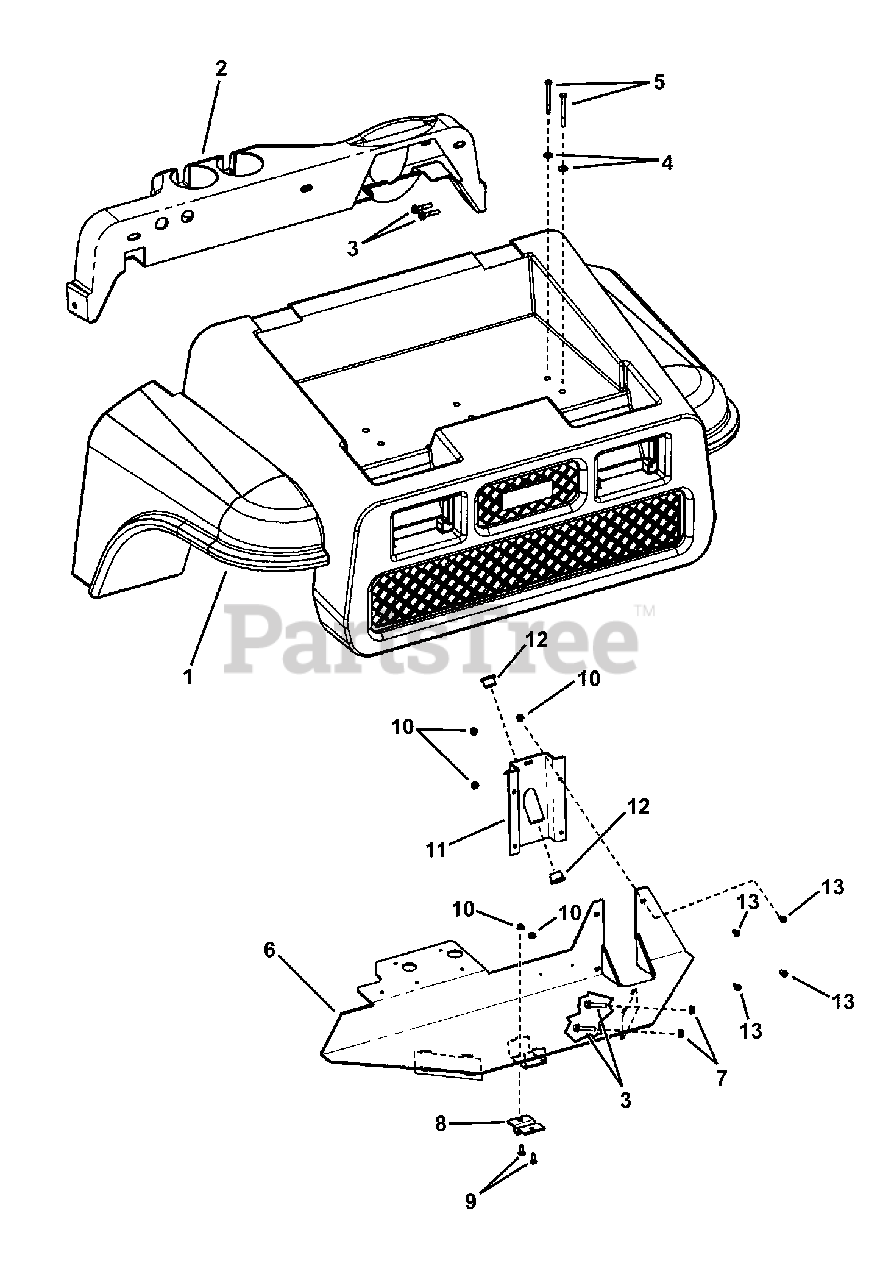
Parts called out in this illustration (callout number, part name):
1	FENDER, UV-2
2	DASH, UV-2
3	BOLT, 5/16-18 x 1-1/2" Hex Flange Lock, GR 5
4	WASHER, .281 x .750 x .051 Flat
5	SCREW, 1/4-20 x 3" Hex Head Cap, GR 5
6	WELDMENT, Steering Support
7	NUT, 5/16-18 Hex Flange Lock, GR 5
8	PIVOT BRACKET, Throttle
9	BOLT, 1/4-20 x 3/4" Square Neck Carriage, GR 5
10	NUT, 1/4-20 Hex Flange Lock, GR 5
11	WELDMENT, Column Support
12	BEARING, .750 I.D.
13	SCREW, 1/4-20 x 1/2" Pan Head Machine
